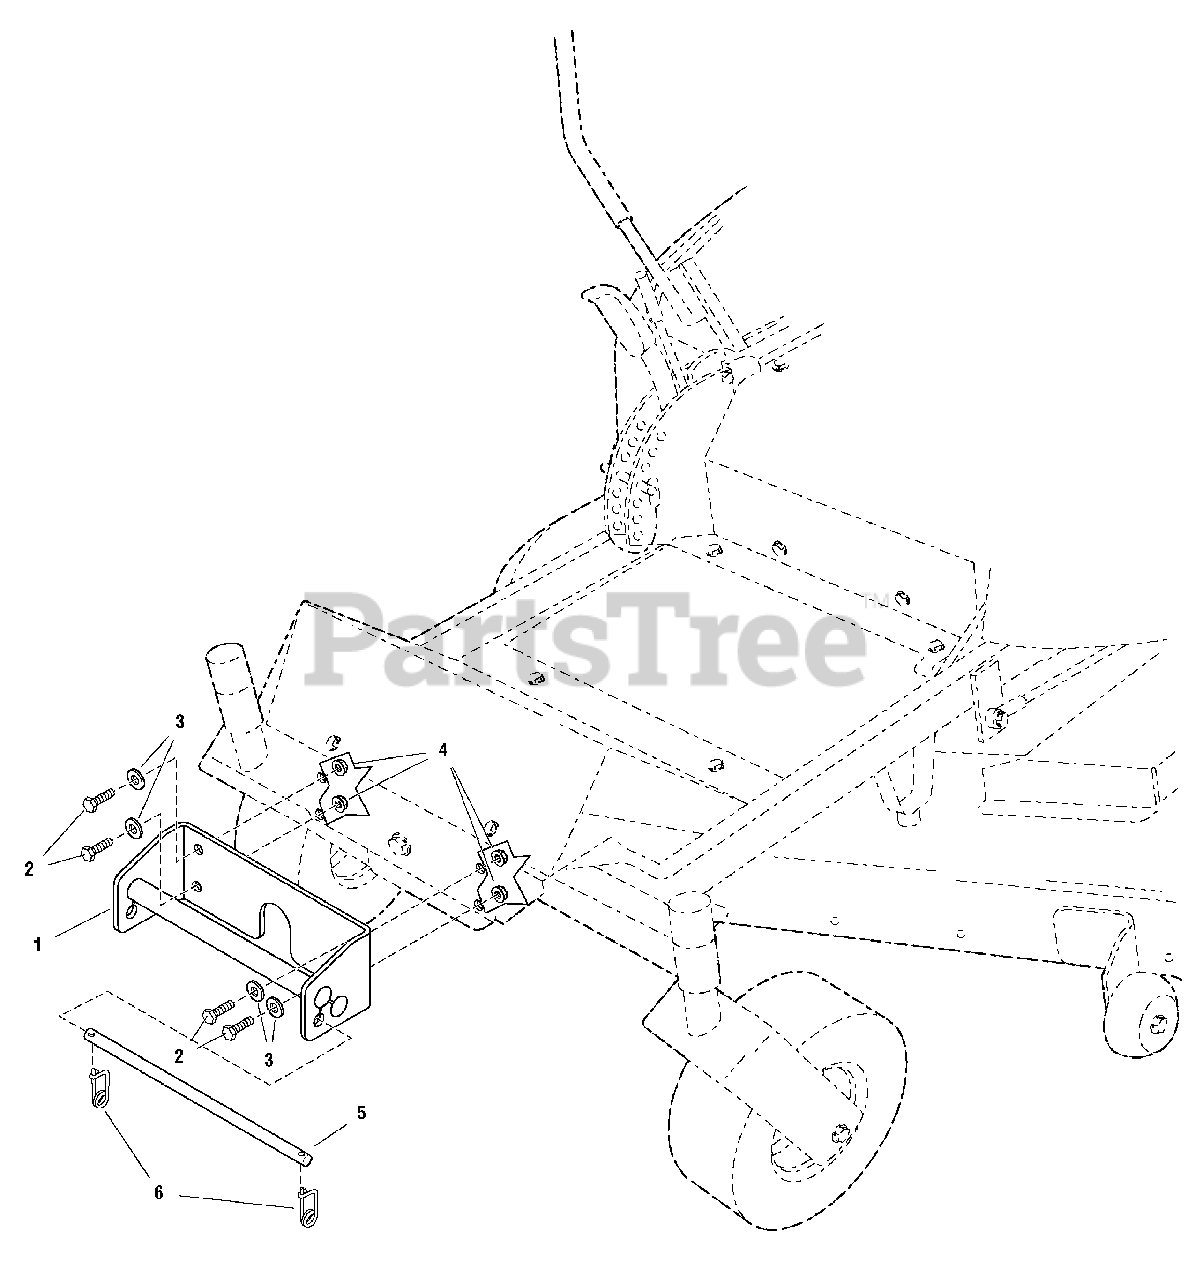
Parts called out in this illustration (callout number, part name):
1	HOLDER ASSEMBL, Weight
2	CAPSCREW, Hex Head, 5/16-18 x 1 1/4
3	WASHER, 5/16
4	NUT, Hex Flange Whiz Lock, 5/16-18 Large Black
5	ROD, Retaining, 1/2 x 13-3/4LG
6	RETAINER, Pin, Spring
